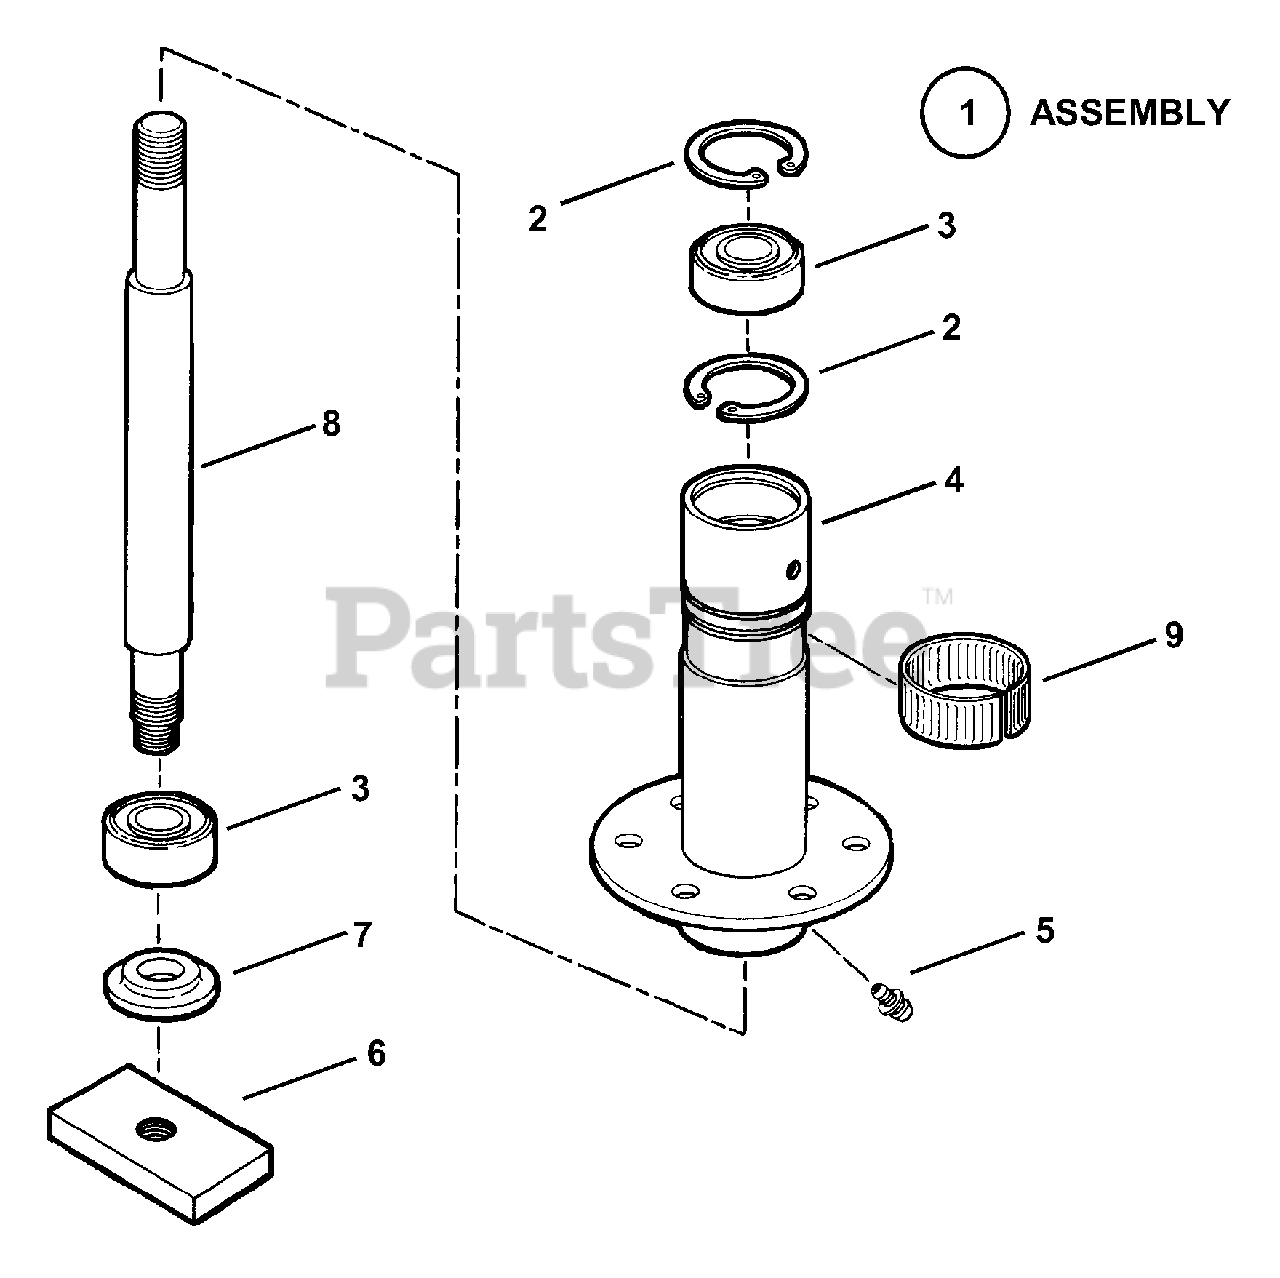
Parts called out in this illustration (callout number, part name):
1	ASSEMBLY, Spindle Housing
2	RING, 1.75" Internal Retaining
3	BEARING, Spindle
4	HOUSING, Spindle (weldment)
5	FITTING, Lube (Press fit for .187 hole-no ball)
6	HOLDER, Blade
7	WASHER, Spindle
8	SPINDLE (9.5" Length)
9	RING, Tolerance
